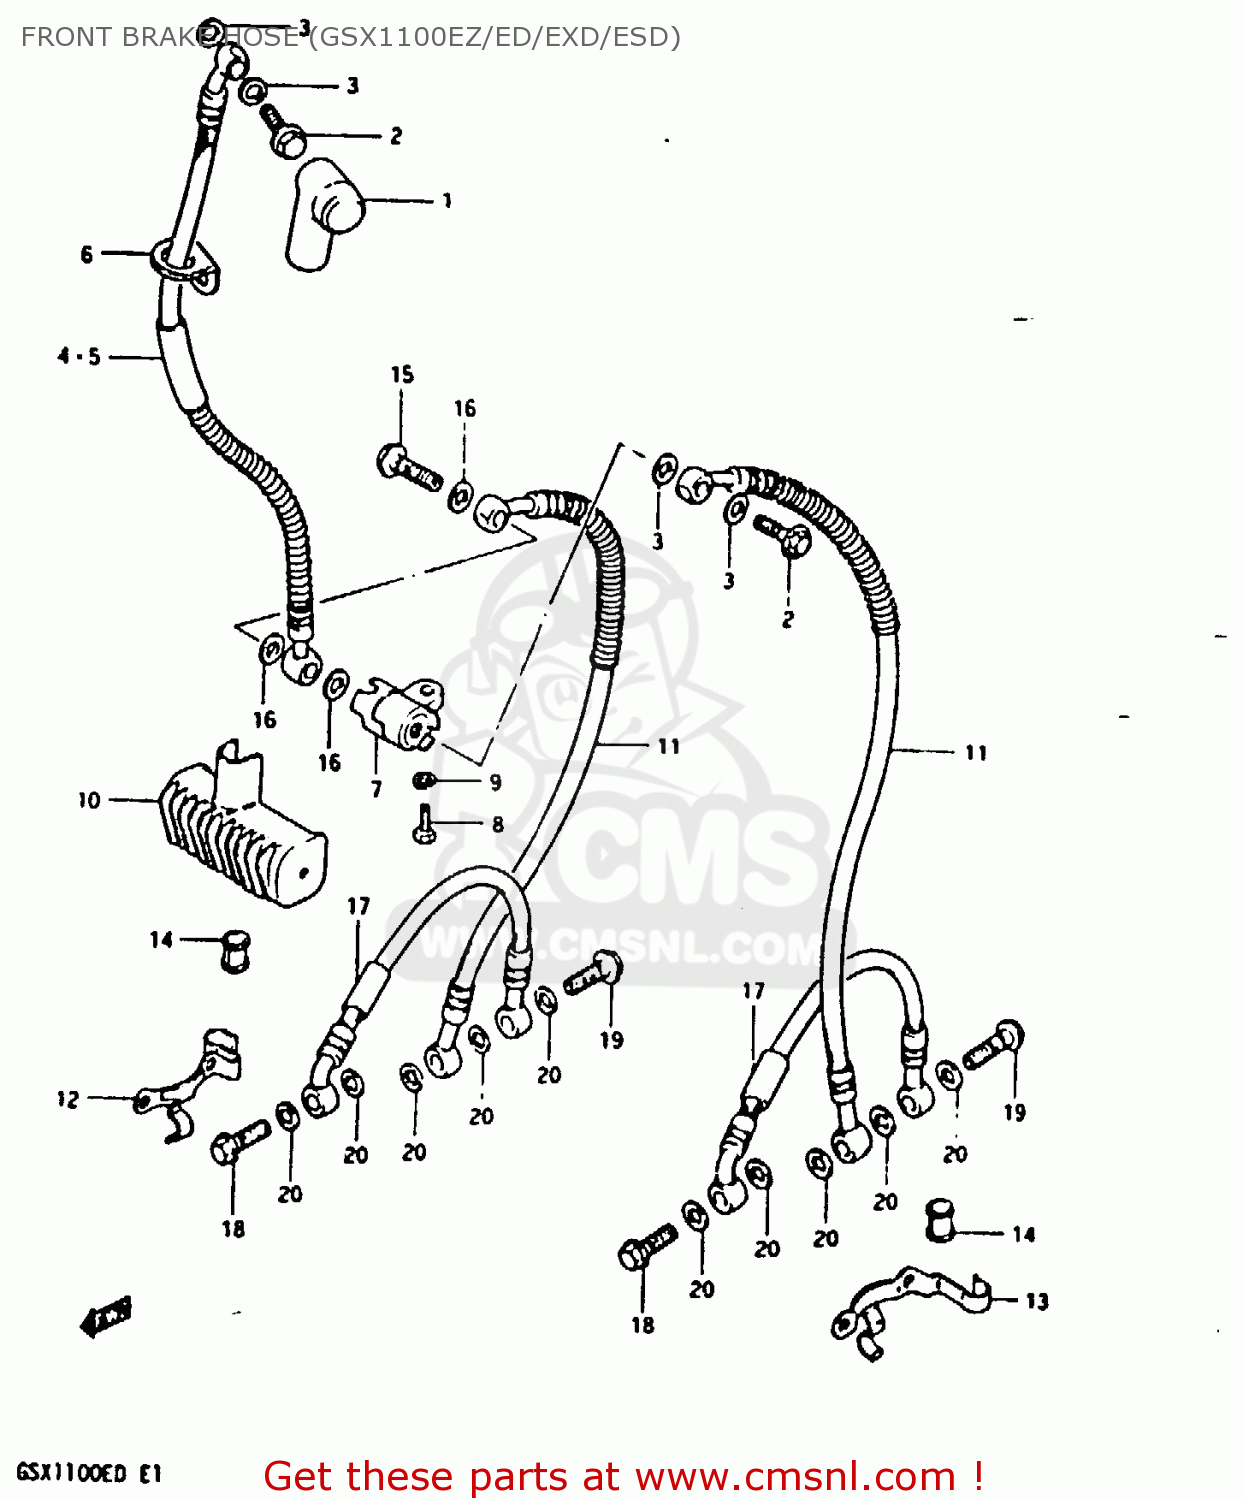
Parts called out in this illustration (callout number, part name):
1	BOOT,MASTER CYLINDER
2	BOLT,UNION
3	WASHER
4	HOSE,FRONT BRAKE
5	HOSE,FRONT BRAKE
6	GUIDE,BRAKE HOSE NO.1
7	JOINT,BRAKE HOSE
8	BOLT
9	LOCK WASHER
10	COVER,BRAKE HOSE JOINT
11	HOSE,FRONT BRAKE
12	CLAMP,BRAKE HOSE,RIGHT
13	CLAMP,BRAKE HOSE,LEFT
14	BUSH,BRAKE HOSE GUIDE,NO.2
15	BOLT,UNION
16	WASHER
17	HOSE,ANTI-NOSE DIVE
18	BOLT,UNION
19	BOLT,UNION
20	WASHER
